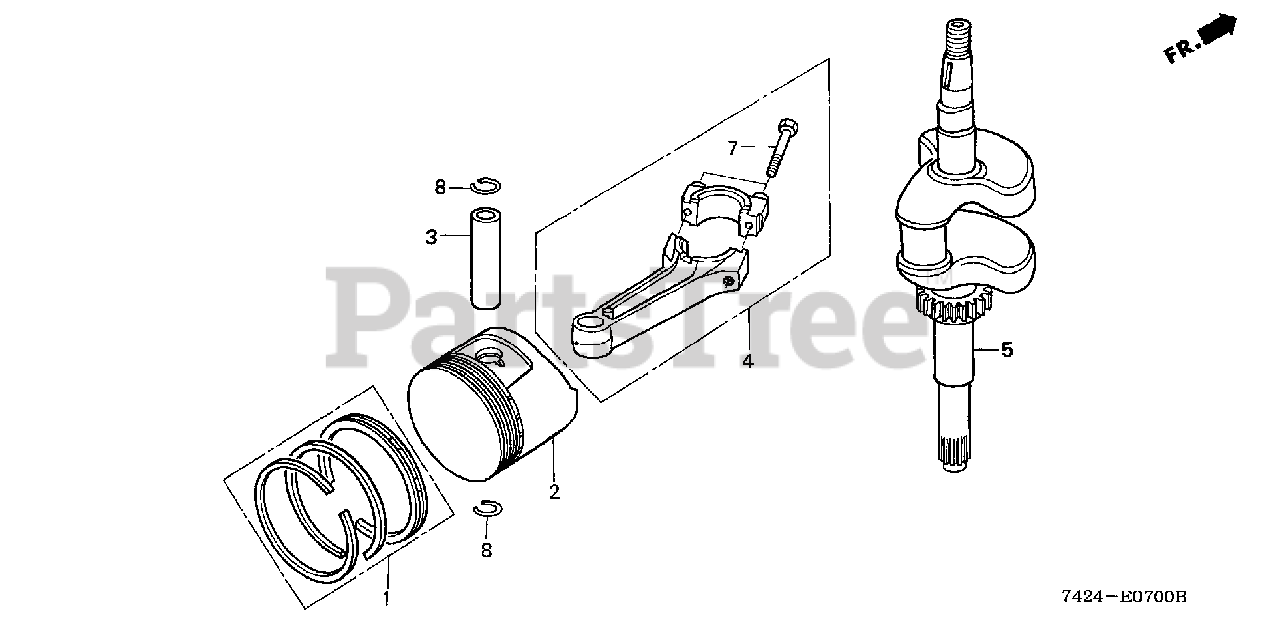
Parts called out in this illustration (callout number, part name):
1	RING SET, PISTON (STD)
1	RING SET, PISTON (OS 0.25)
1	RING SET, PISTON (OS 0.50)
1	RING SET, PISTON (0.75)
2	PISTON (STD)
2	PISTON (OS 0.25)
2	PISTON (OS 0.50)
2	PISTON (0.75)
3	PIN, PISTON
4	ROD ASSY., CONNECTING
4	ROD ASSY., CONNECTING (US 0.25)
5	CRANKSHAFT
7	BOLT, CONNECTING ROD
8	CLIP, PISTON PIN (13MM)
